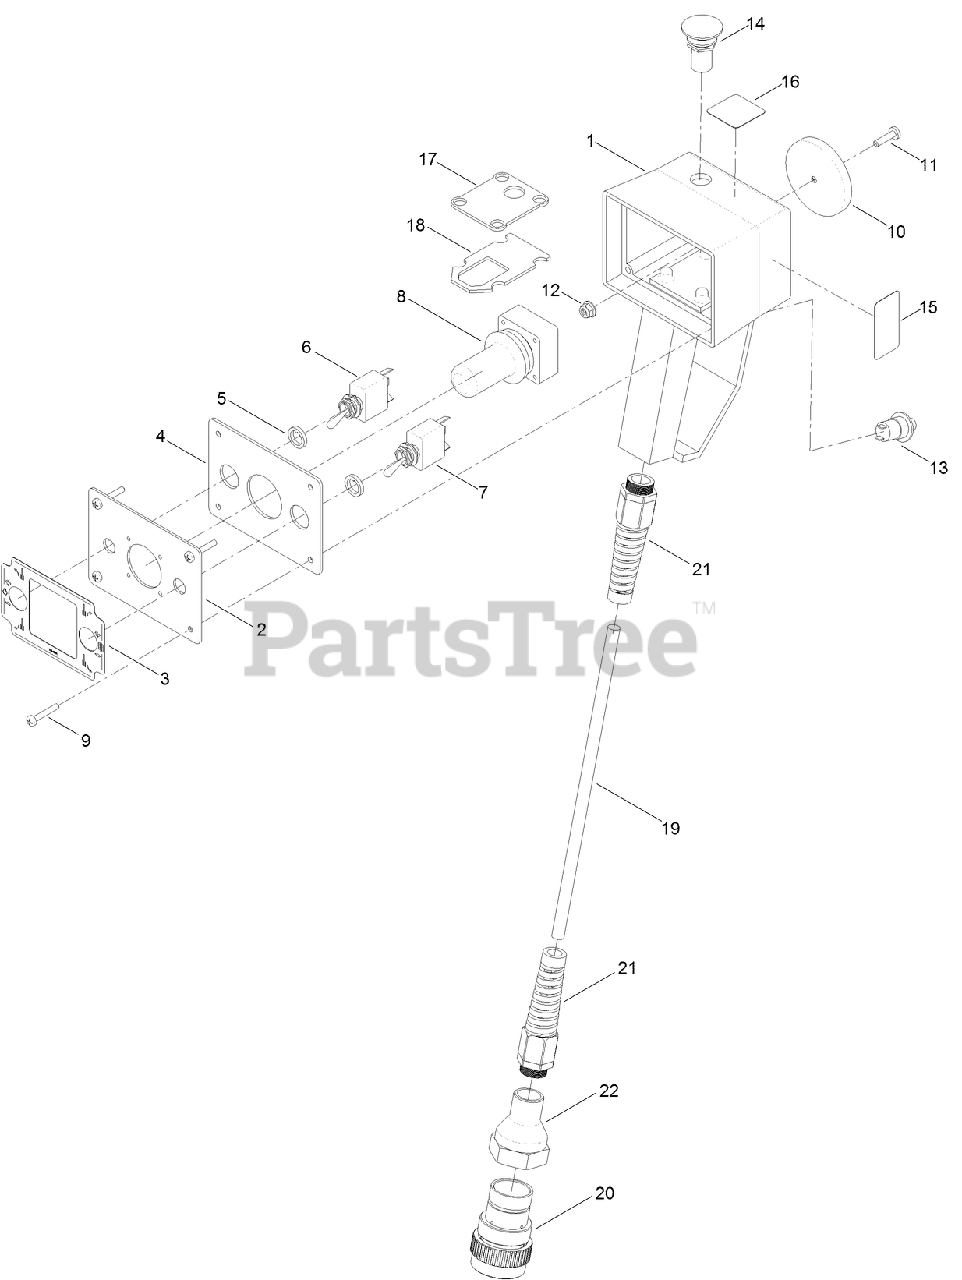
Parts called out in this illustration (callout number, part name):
1	ENCLOSURE-HANDHELD
2	PLATE-PENDANT FRONT
3	DECAL-TRAVEL PENDANT
4	GASKET-PENDENT FRONT
5	SEAL-SWITCH
6	SWITCH
7	SWITCH
8	JOYSTICK
9	SCREW-PPH
10	MAGNET-CERAMIC, ENCASED
11	SCREW-PPH
12	NUT-HF
13	SWITCH-MOMENTARY
14	SWITCH-PUSH BUTTON
15	DECAL-OPERATOR PRESENCE
16	DECAL-EMERGENCY STOP
17	GASKET-HANDLE, INNER
18	GASKET-HANDLE, OUTTER
19	CABLE-TRAVEL PENDANT
20	PLUG-CONNETOR
21	GRIP-CORD
22	COUPLER
